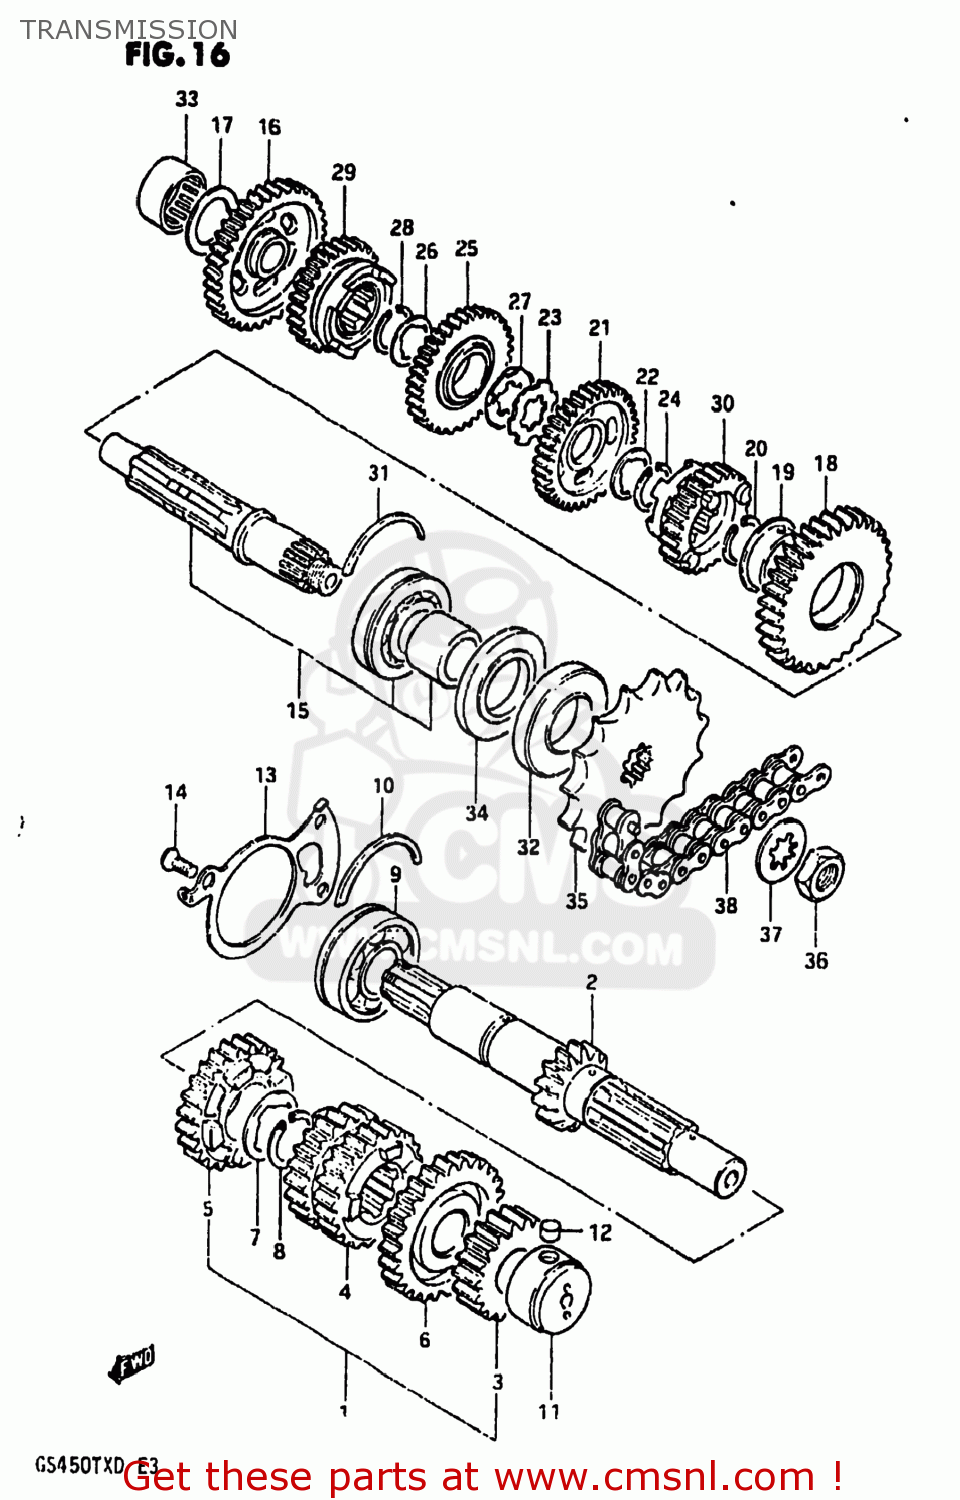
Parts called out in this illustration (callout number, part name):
1	SHAFT,COUNTER
2	SHAFT,COUNTER
3	GEAR,2ND DRIVE(NT:18)
4	GEAR,THIRD DRIVE
5	GEAR,FIFTH DRIVE
6	GEAR,SIXTH DRIVE
7	WASHER
8	CIRCLIP
9	BEARING(25X62X17)
10	C-RING
11	ROLLER BEARING (20X34X2
12	PIN
13	PLATE,COUNTERSHAFT BEARING
14	SCREW
15	SHAFT,DRIVE
16	GEAR,FIRST DRIVEN
17	WASHER
18	GEAR,SECOND DRIVEN
19	BUSHING
20	CIRCLIP
21	GEAR,THIRD DRIVEN
22	WASHER,LOCK
23	WASHER,LOCK
24	CIRCLIP
25	GEAR,FOURTH DRIVEN
26	WASHER,LOCK
27	WASHER
28	CIRCLIP
29	GEAR,5TH DRIVEN(NT:25)
30	GEAR,SIXTH DRIVEN
31	C-RING
32	SEAL,OIL(32X62X7)
33	ROLLER BEARING (20X34X1
34	SEAL,OIL(32X62X5.5)
35	SPROCKET,ENGINE(NT:16)
36	NUT
37	WASHER
38	CHAIN,DRIVE #50UB-108
